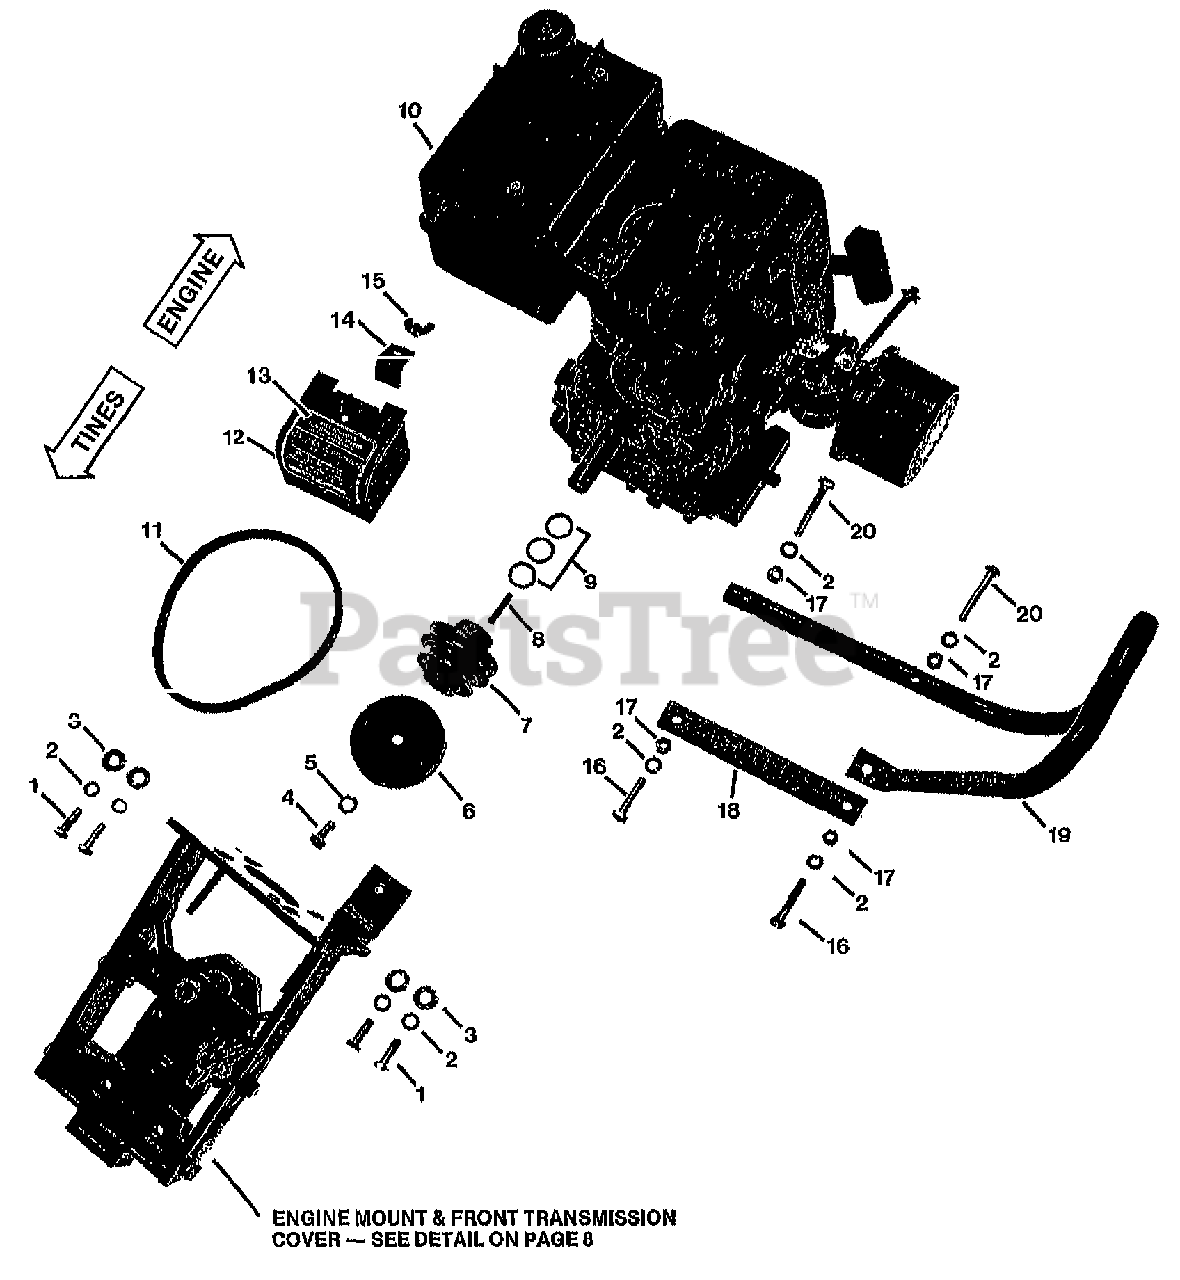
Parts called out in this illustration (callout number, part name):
1	SCR 5/16-24 X 1
2	WASHER-LK .312 ZP
3	WASHER-.88X312X.08 ZP
4	BOLT-HH 3/8-24 X .75 ZP
5	WASHER-LK .375 @ DEPL
6	DISC-REV
7	PULLEY-ENG MACH
8	KEY-.188 SQ X 1.25
9	SHIM-1.0X.7656X.062
10	ENGINE - TECUMSEH
10	ENGINE - STANDARD RECOIL START
10	ENGINE - 3.5 HP, MODEL H35,
10	ENGINE - TYPE 45564N
12	BELT SHROUD W/DECAL
13	DECAL-BELT COVER
15	NUT-WING/LK 1/4-20 ZP
16	SCR-HH 5/16-18X1.75
17	NUT-HEX 5/16-18 ZP
18	PAD-ENG JACKING
19	GUARD-CARBURETOR PNT
20	BOLT-HH 5/16-18X2 ZP
